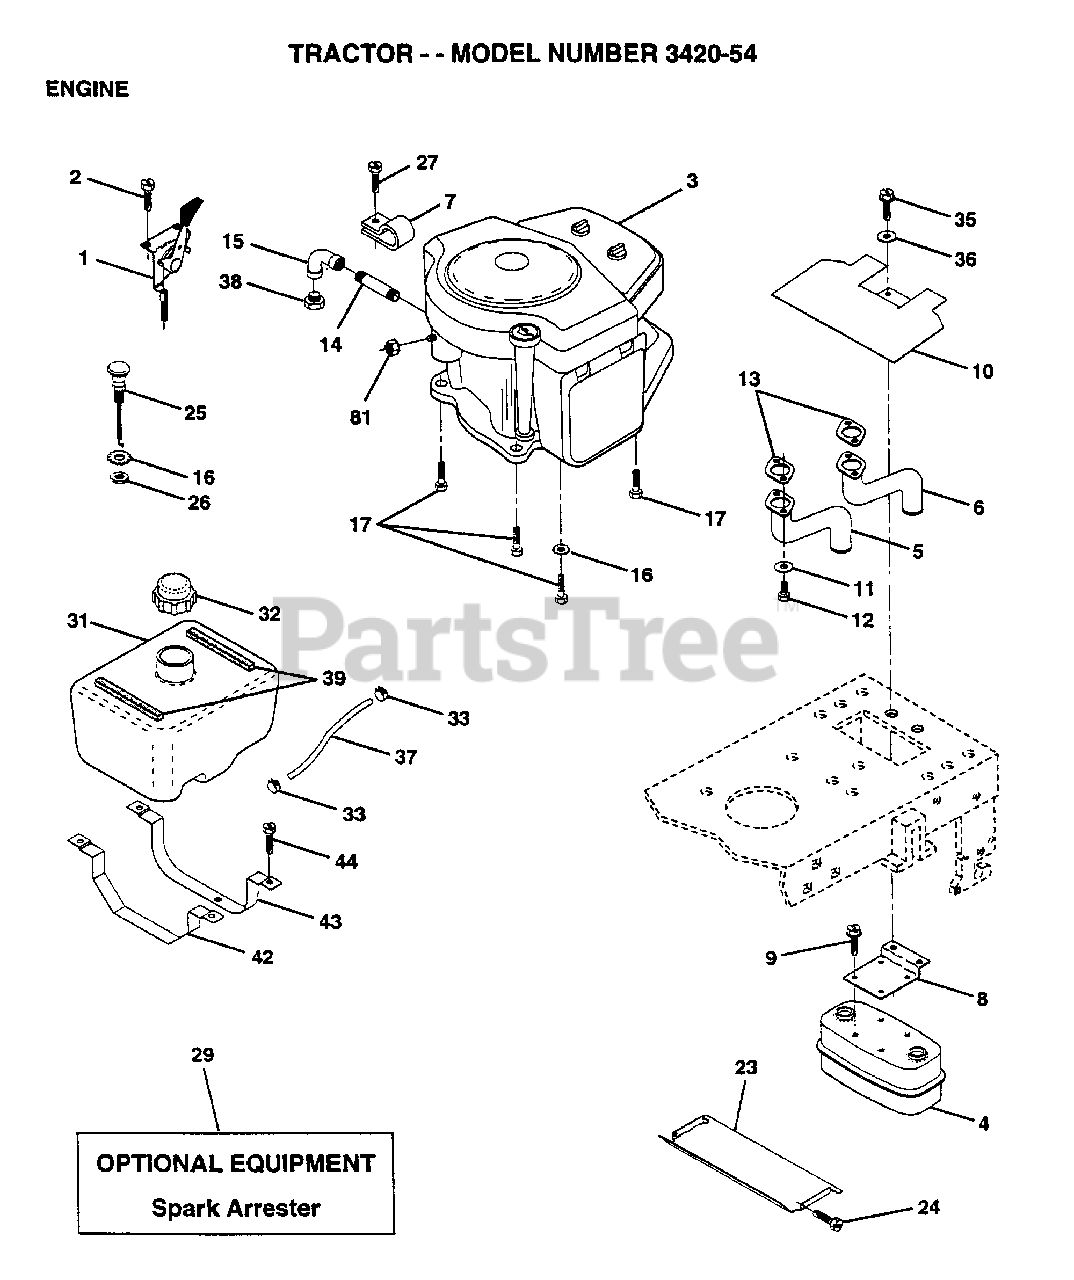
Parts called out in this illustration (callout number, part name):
2	SCREW LT
3	ENGINE B&S 16HP
5	EXHAUST.B&S.18.LH
6	EXHAUST.B&S.18.RH
7	CLAMP.TUBE.DBL.EN
8	BRACKET MUFFLER
9	SCREW ST
10	SHIELD.HEAT.
11	LOCKWASHER
14	PIPE NIPPLE LT
15	ELBOW
16	LOCKWASHER
17	SCREW LT
23	HEAT SHIELD
24	SCREW
25	"CONTROL.CHOKE.51"""
27	SCREW.10-24X1/2
31	TANK FUEL 1.9 NAT
32	CAP ASM FUEL
33	HOSE CLAMP
35	SCREW
36	WASHER
37	HOSE T
39	"STRIP,FORM"
42	STRAP TANK FUEL
43	STRAP TANK FRONT
44	SCREW
81	NUT
